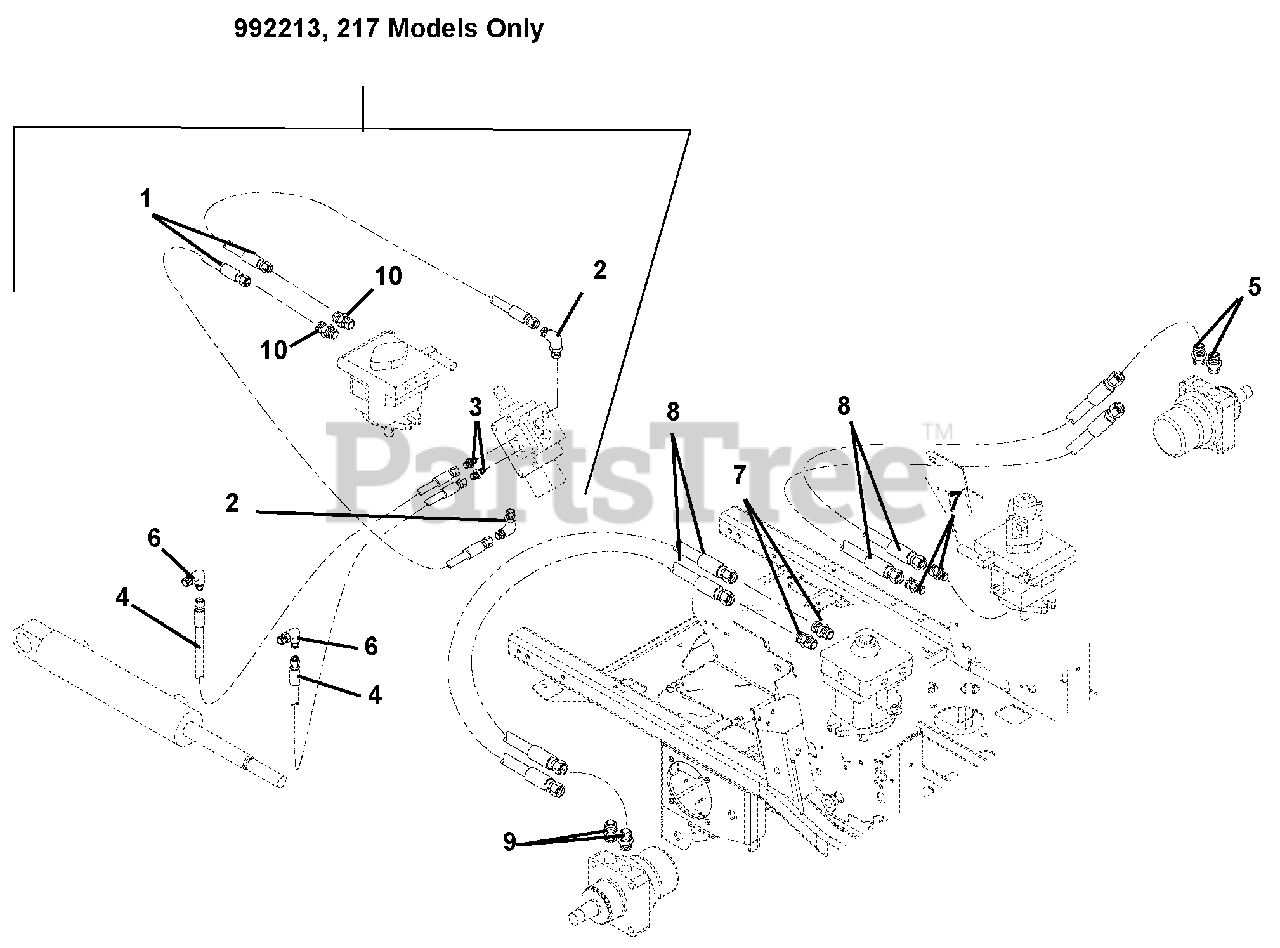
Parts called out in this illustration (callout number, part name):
1	Hose, Hydraulic (992213, 217)
2	Hydraulic, Fitting Elbow (992213, 217)
3	Adapter (4-6F5OLO) (992213, 217)
4	Hose, Hydraulic (992213, 217)
5	Fitting, Hydraulic Straight (8-10 F5OLO-S)
6	Fitting, Hydraulic (4 C5OLO) (992213, 217)
7	Adapter, Face Seal 8 x 8 .50 O-Ring
8	Hose, Hydraulic .50
9	Adapter, Hydraulic Steel (M10 O-M8F)
10	Fitting, Hydraulic (4 F5OLO) (Supplied with pump) (992213, 217)
